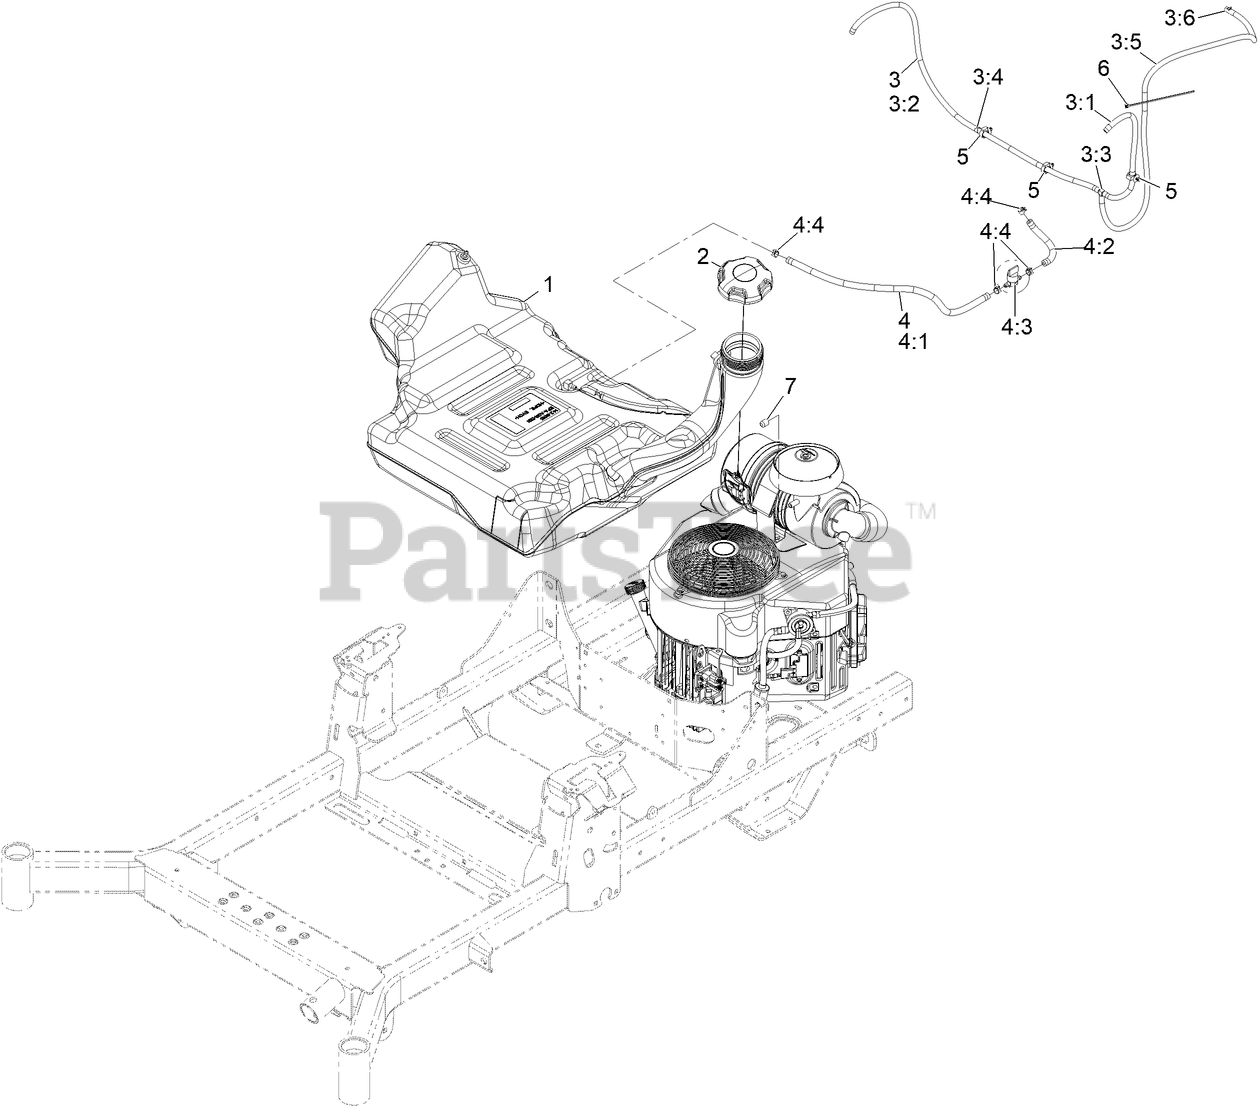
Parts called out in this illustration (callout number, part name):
1	ASM-FUEL TANK
2	CAP-FUEL, RATCHETING
3	Vent Hose ASM
3:1	HOSE-FUEL
3:2	HOSE-LP
3:3	FITTING-TEE
3:4	Clamp Hose
3:5	Hose-Fuel
3:6	CLAMP-HOSE
4	FUEL HOSE ASM
4:1	HOSE-FUEL
4:2	HOSE-FUEL
4:3	VALVE-FUEL
4:4	CLAMP-HOSE
6	TIE-CABLE
7	PLUG-PORT
